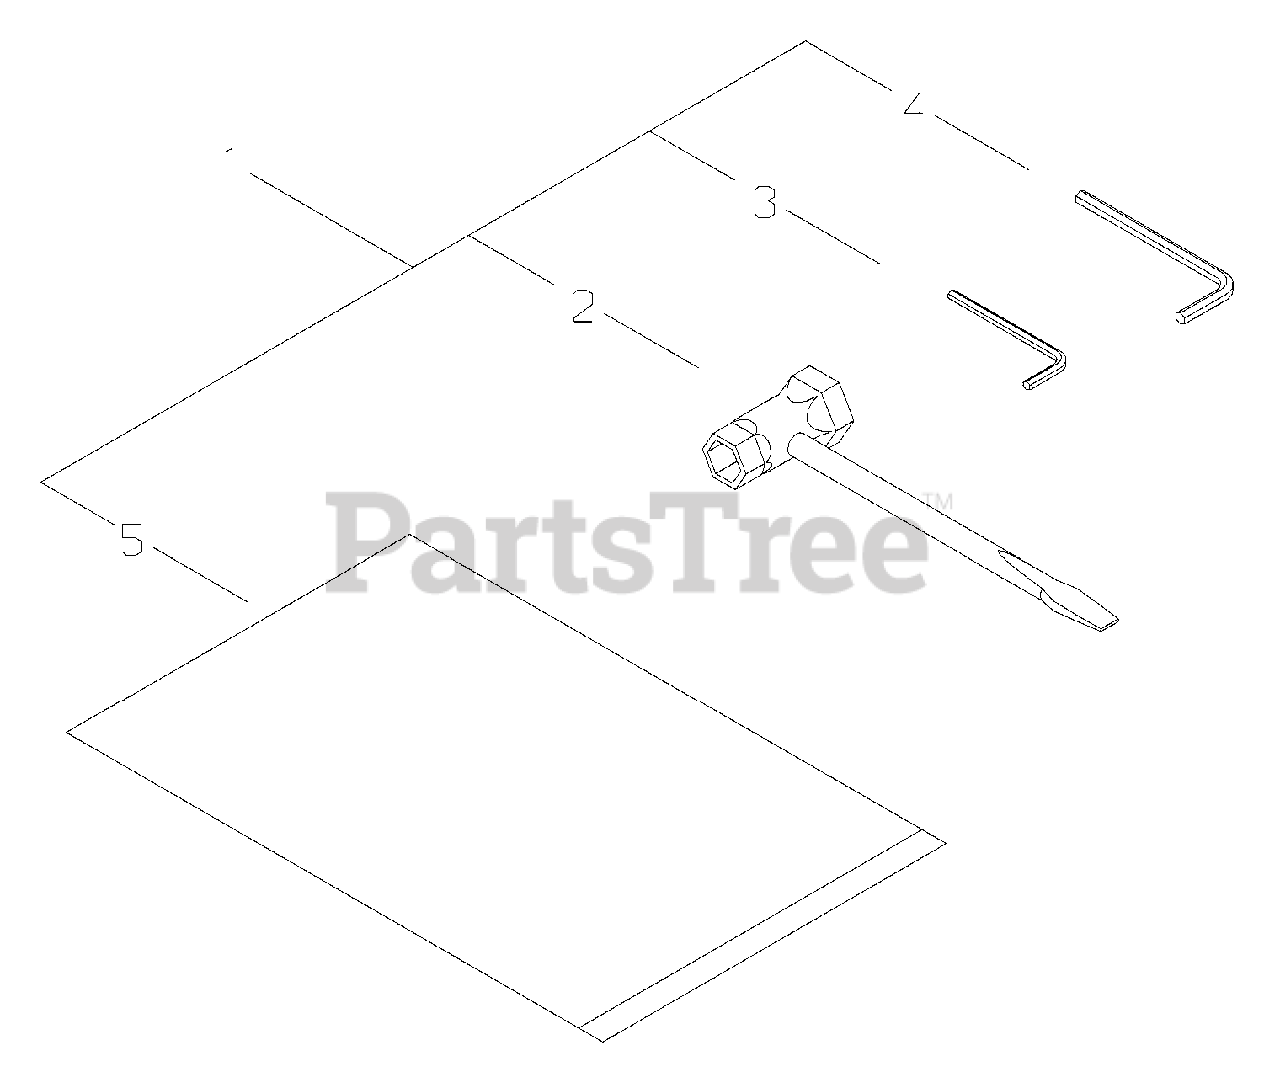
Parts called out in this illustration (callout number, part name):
1	TOOL KIT, SERVICE
2	T-WRENCH 13×19 MM
3	WRENCH, ALLEN 3 MM
